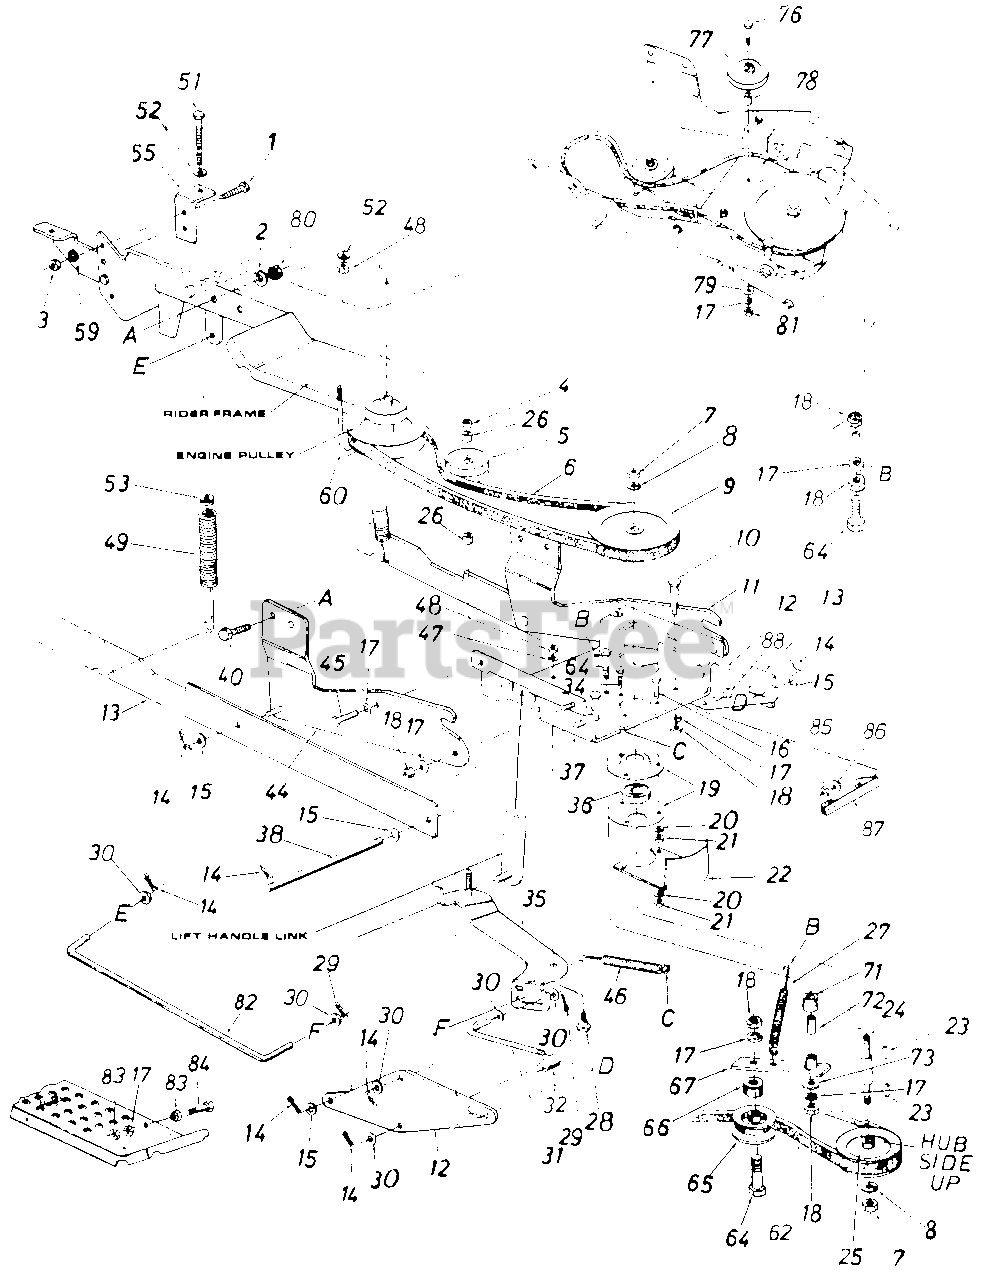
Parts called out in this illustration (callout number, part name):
1	Hex Bolt 1/4-28 x 1.0" Lg.- Gr. 5
2	L-Wash. 1/4" I.D.
3	Hex Nut 1/4-28 Thd.
4	Hex Cent. L-Nut 3/8-16 Thd.
5	Idler Pulley
6	"V"-Belt
7	Hex Jam Nut 5/8-11 Thd.
8	L-Wash. 5/8" I.D.
9	5/8 Pulley x 6.5" O.D.
10	Shoulder Bolt
11	Channel Support Brkt.- R.H.
12	Linkage Brkt.
13	Linkage Arm Ass'y.
14	Intern. Cotter Pin .50" Dia.
15	Fl-Wash.
16	Hex Bolt 5/16-18 x 1.25" Lg.
17	L-Wash. 3/8" I.D.
18	Hex Jam Nut 3/8-16 Thd.
19	Bearing Housing
20	L-Wash. 5/16" I.D.
21	Hex Nut 5/16-18 Thd.
24	Pulley Spindle
25	5/8 Pulley 6.28" I.D. x 5.56" O.D.
26	Spacer .383" I.D. x .503" O.D. x .562" Lg.
27	Extension Spring .54" O.D. x 5.25"
28	Shoulder Bolt
29	Cotter Pin 3/32" Dia.
30	Fl-Wash.
31	Control Rod (Clutch)
32	Ferrule
34	Hex Sems Bolt 5/16-18 x .75" Lg.
35	Clutch Idler Brkt. Ass'y.
36	Ball Bearing
37	Channel Ass'y.
38	Lift Handle Shaft
40	Hex Self-Tap Scr. 1/4-20 x .75" Lg.
44	Channel Supporting Brkt.- L.H.
45	Hex Bolt 3/8-16 x 1" Lg.
46	Extension Spring
47	L-Wash. 5/16" I.D.
48	Hex Nut 5/16-18 Thd.
49	Helper Spring
51	Hex Bolt 5/16-1S x 2.0" Lg.
52	Bell-Wash. .345" I.D. x .88" O.D. x .06"
53	Spring Insert
60	J-Bolt 5/16-18 Thd.
62	"V"-Belt
64	Hex Bolt 3/8-16 x 2" Lg.
65	Idler Pulley
66	Spacer .385" I.D. x .503" O.D. x .562" Lg.
67	Idler Arm Ass'y.
71	Spacer .38" I.D.
72	Spacer .3775" I.D. x .6" O.D. x 8.3" Lg.
73	Fl-Wash. 3/8" I.D. x 1" O.D. x 1.27"
76	Hex Bolt 3/8-16 x 2.5" Lg. (Grade 5)
77	Idler Pulley .38" I.D. x 3.06" O.D.
78	Spacer .385" I.D. x .63" O.D. x .76" Lg.
79	Fl-Wash. .39" I.D. x 1-3/4" O.D. x 3/16"
80	Hex L-Nut 1/4-20 Thd.
81	Hex Nut 3/8-16 Thd.
82	Clutch Control Rod
83	Hex Nut 3/8-24 Thd.
84	Hex Bolt 3/8-24 x 2.25" Lg.
85	Hex Nut 3/8-16 Thd.
86	Bell-Wash. 3/8" I.O.
87	Auger Brake Brkt. Ass'y.
88	Hex Bolt 3/8-16 x 5/8" Lg.
